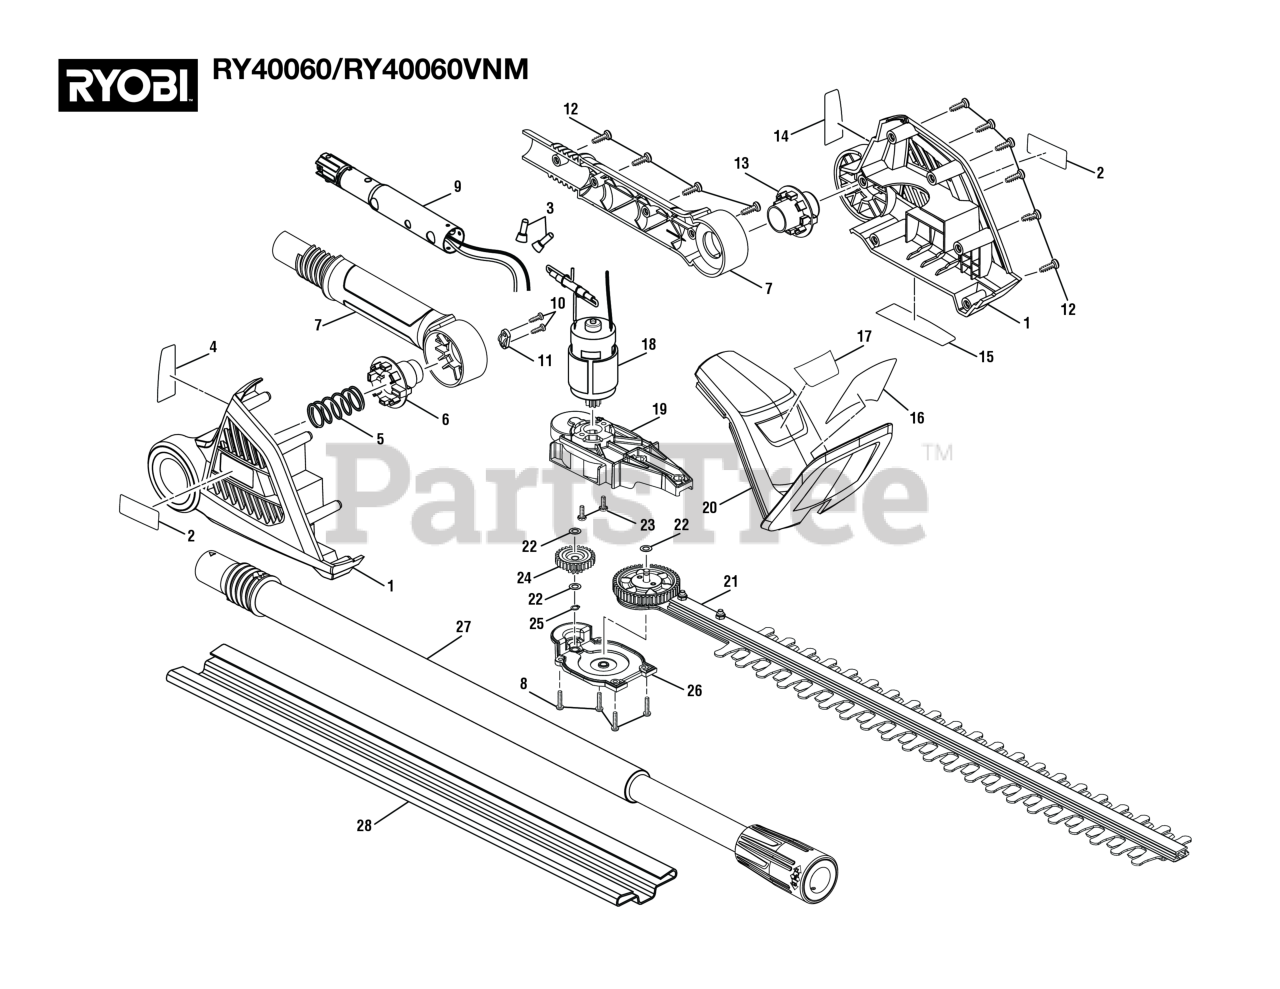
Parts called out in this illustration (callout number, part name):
1	Motor Housing Assembly
2	Logo Label
3	Wire Connector (Closed End)
4	Warning Icons Label (Left)
5	Compression Spring (Pivot Button)
6	Pivot Button (Right)
7	Pole Housing Assembly
8	Screw (M4 x 16 mm, Pan Hd.)
9	Lower Boom Assembly
10	ST SCREW BH BM X 10
11	Cord Clamp
12	Screw (M4 x 14 mm, T15 Torx Pan Hd.))
13	Pivot Button (Left)
14	Warning Icons Label (Right)
15	Data Label
16	Danger Warning Label
17	40V Lithium-Ion Label
18	Motor Assembly
19	Gear Box Base
20	Motor Cover and Guard Assembly
21	Blade Assembly
22	Washer (M6, ID6.2 x 11OD x 0.3t)
23	Screw w/Tooth Washer (M4 x 12 mm, Pan Hd.)
24	Center Gear
25	RETAINING RING (EXTERNAL)
26	Gear Box Cover Assembly
27	Extended Boom Assembly
